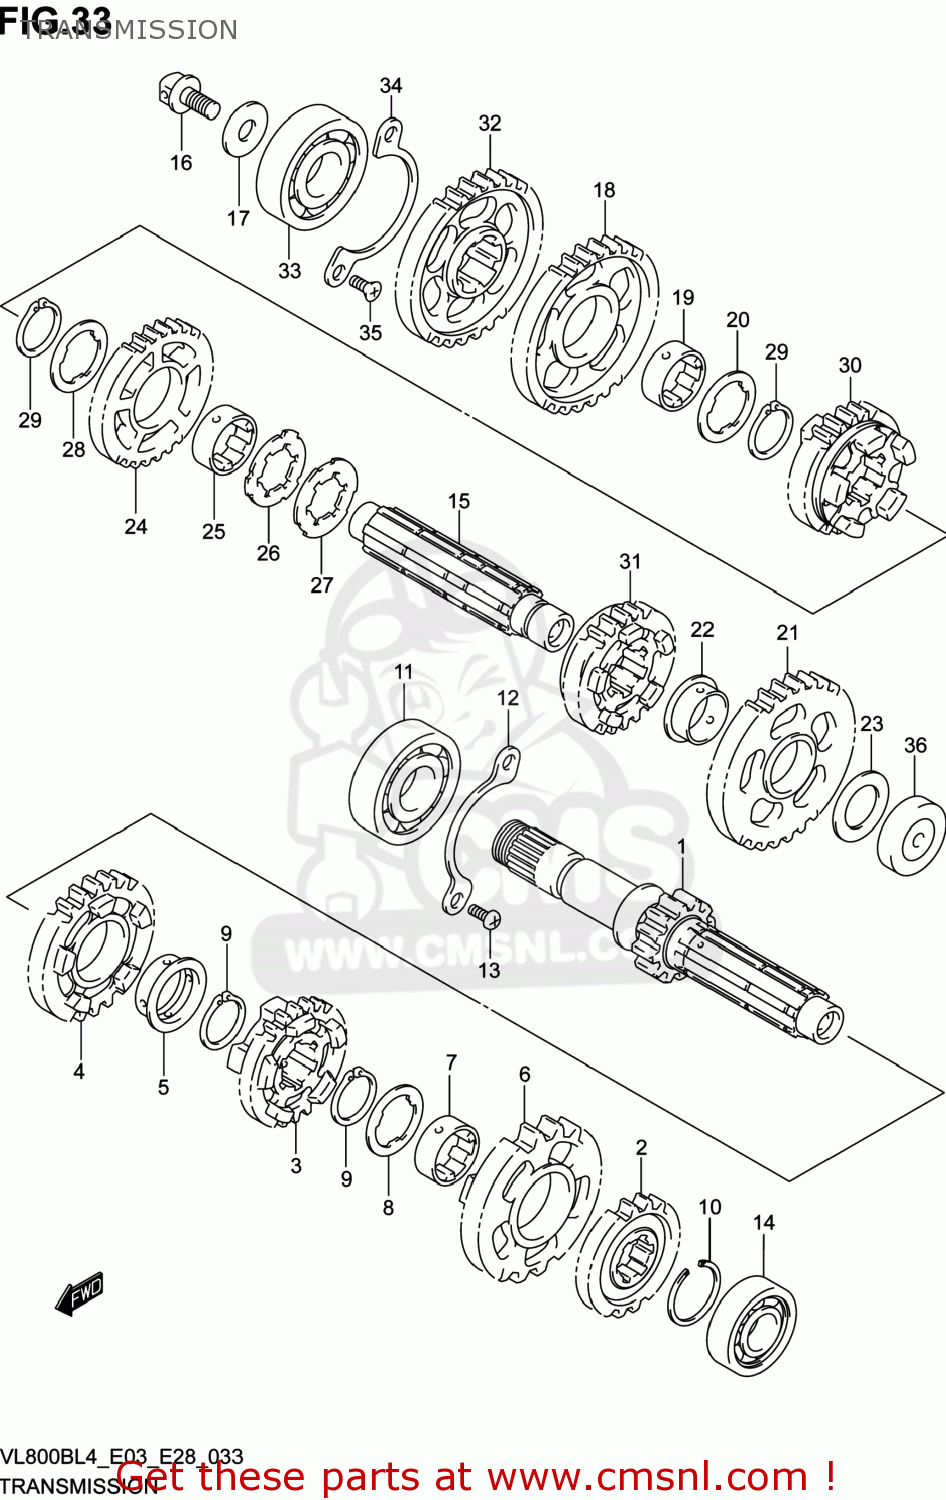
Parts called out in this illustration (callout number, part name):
1	SHAFT,COUNTER
2	GEAR,2ND DRIVE(NT:19)
3	GEAR,3RD DRIVE(NT:22)
4	GEAR,4TH DRIVE(NT:25)
5	BUSH
6	GEAR,5TH DRIVE(NT:27)
7	BUSH,6TH DRIVE GEAR
8	WASHER,LOCK
9	RING,SNAP
10	CIRCLIP
11	BEARING(25X62X17)
12	RETAINER,CNTR SHAFT BEARING
13	SCREW(6X12)
14	BEARING(20X47X14)
15	SHAFT,DRIVE
16	NOZZLE,DRIVE SHAFT
17	WASHER
18	GEAR,1ST DRIVEN(NT:32)
19	BUSH
20	WASHER,LOCK
21	GEAR,2ND DRIVEN(NT:31)
22	BUSH
23	SHIM(20X34X1)
24	GEAR,3RD DRIVEN(NT:27)
25	BUSH
26	WASHER
27	WASHER,LOCK
28	WASHER,LOCK
29	CIRCLIP
30	GEAR,4TH DRIVEN(NT:25)
31	GEAR,5TH DRIVEN(NT:22)
32	GEAR,REDUCTION DRIVE(NT:30)
33	BEARING(20X52X15)
34	RETAINER,DRIVE SHAFT BEARING
35	SCREW(6X12)
36	BEARING(20X52X15)
